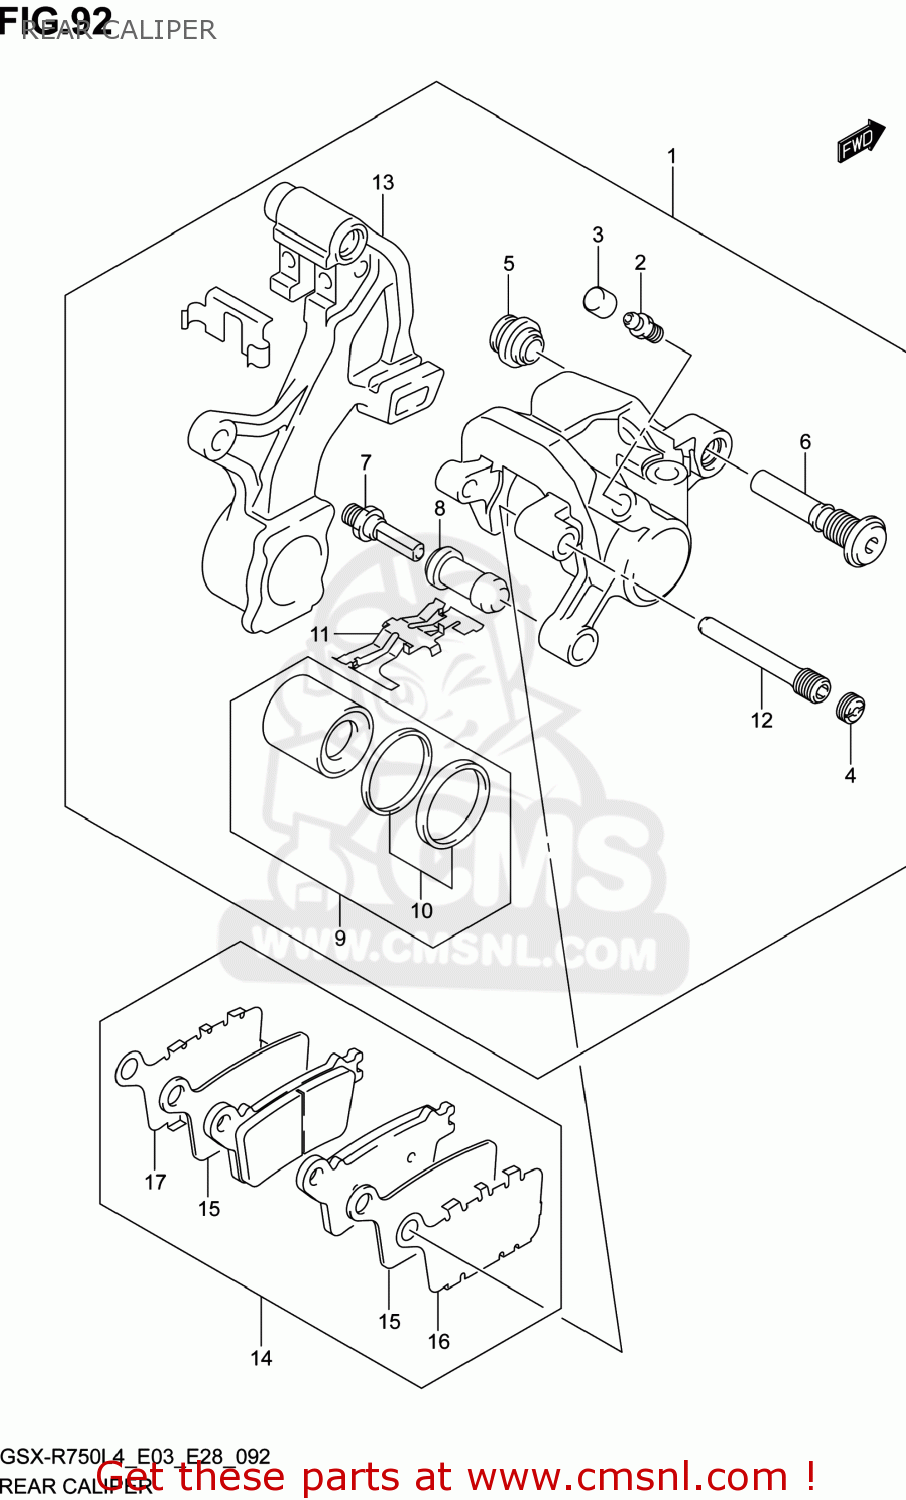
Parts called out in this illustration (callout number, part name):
1	CALIPER ASSY,RR
2	BLEEDER
3	CAP,BLEEDER
4	PLUG,PIN
5	BOOT
6	PIN,BOLT
7	PIN,BOLT
8	BOOT
9	PISTON SET
10	SEAL SET,PISTON
11	SPRING,PAD
12	PIN,PAD
13	BRACKET,RR
14	PAD & SHIM SET (NAS)
15	INSULATOR
16	RETAINER,PAD
17	RETAINER,PAD
